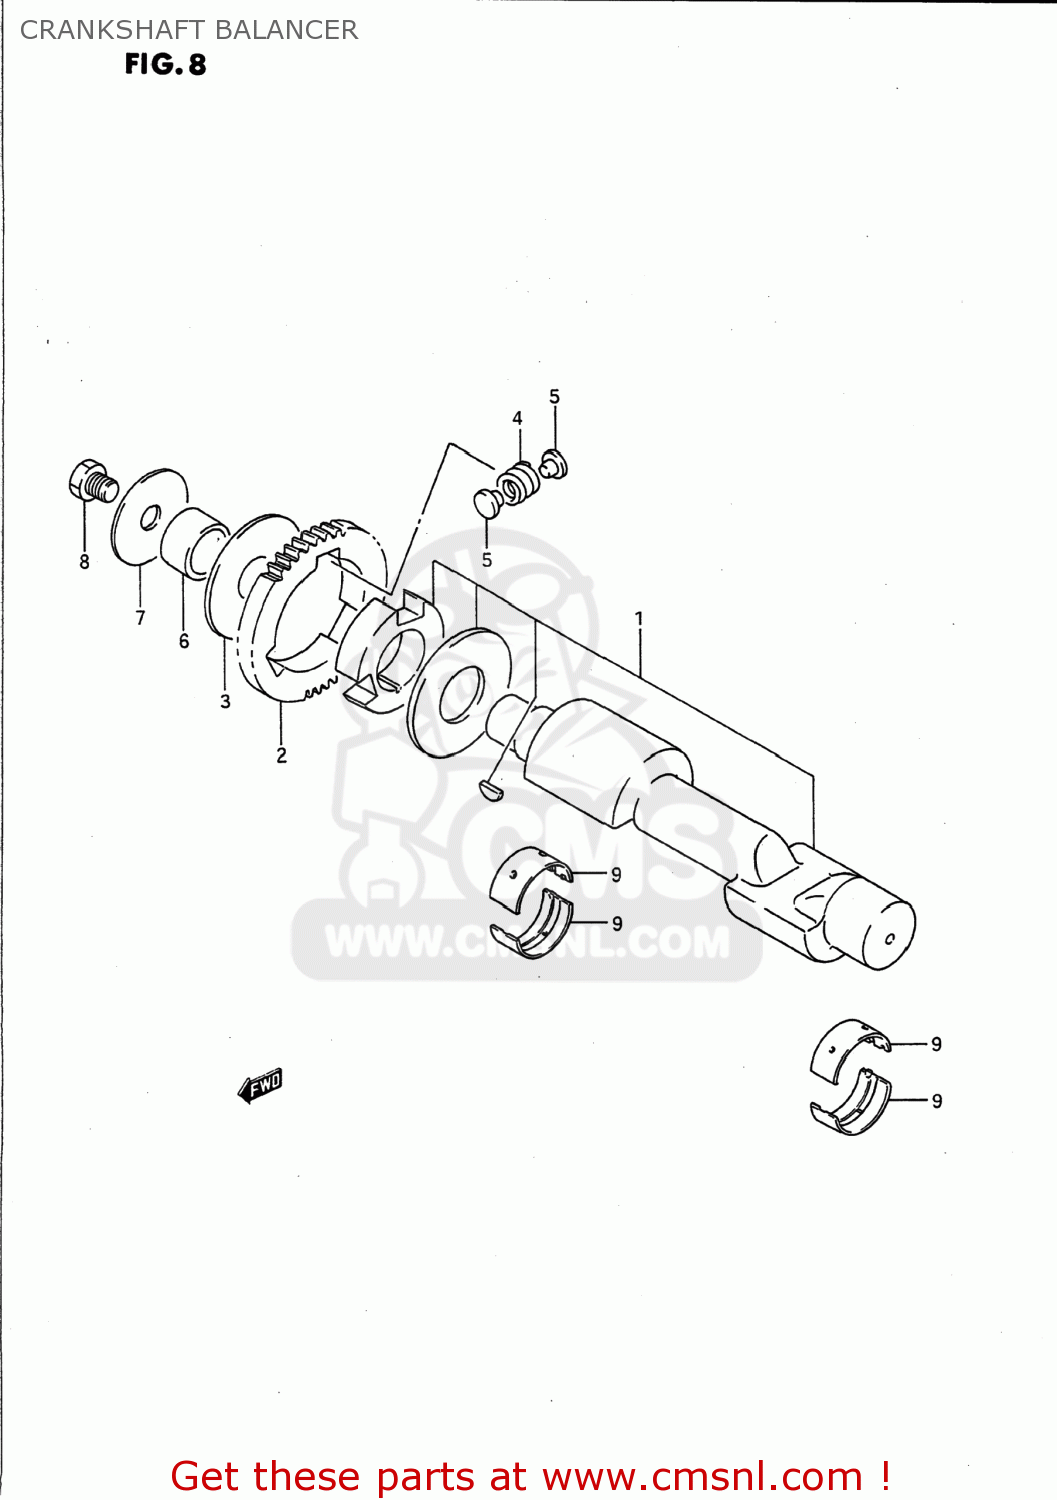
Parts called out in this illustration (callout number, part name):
1	BALANCER,CRANKSHAFT
2	GEAR,CRANK BALANCER DRIVE
3	WASHER(24X70X3)
4	SPRING
5	PIN
6	SPACER
7	WASHER(12X50X3)
8	BOLT
9	BEARING,CRANKSHAFT(GREEN)
